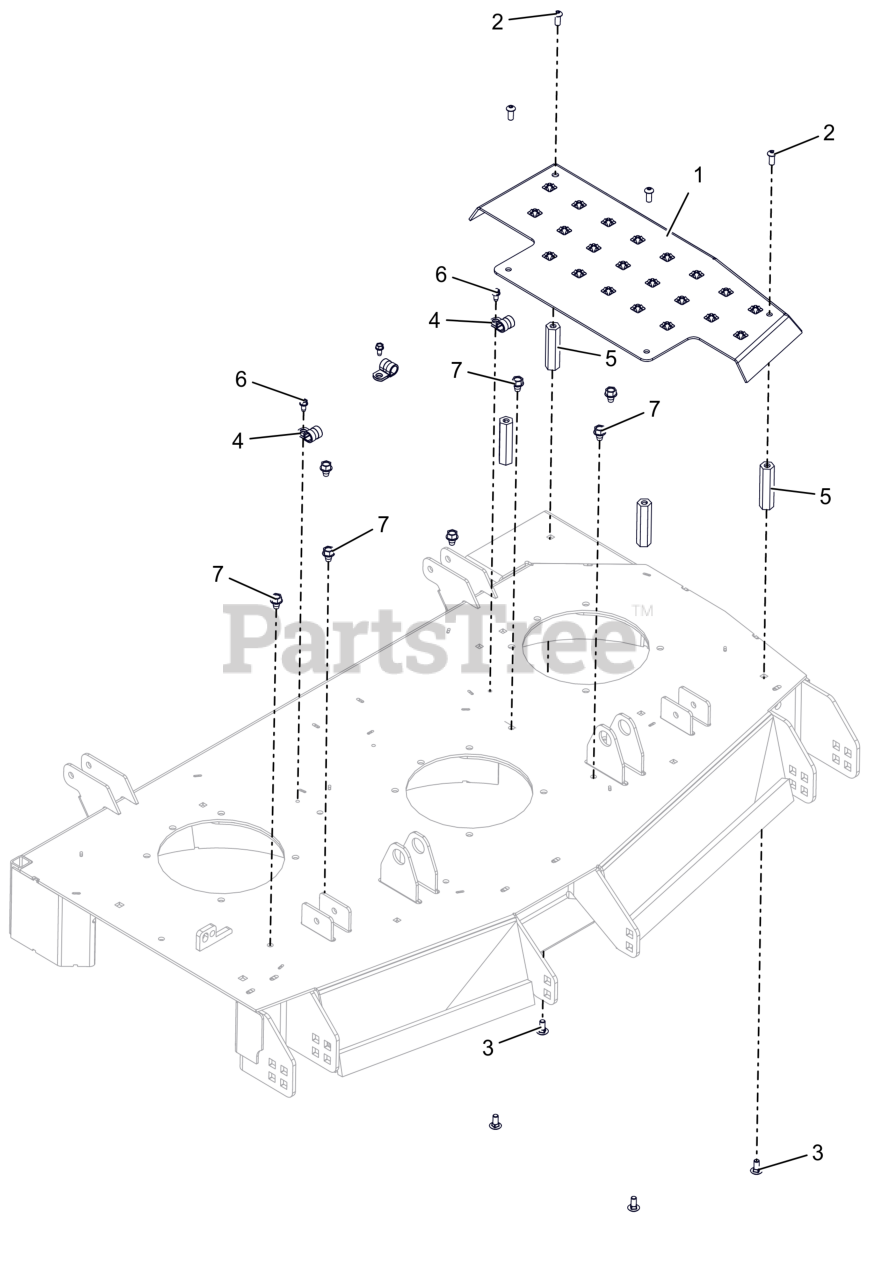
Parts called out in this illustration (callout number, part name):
1	PLATFORM, WLDMT 48 SD DECK STEP (ORANGE)
2	SCR-SKH .31-18X.75 BTNHD YWZC
3	BLT, RHSN .31-18X.75 G5 ZCC LT
4	CLAMP, CUSHIONED STEEL
5	NUT, COUPLING .31-18 X 3.00
6	SCR-TAP .25-20X.50 HWH ZCC
7	SCR,TAP .375-16X.50 HWH TR ZCC
